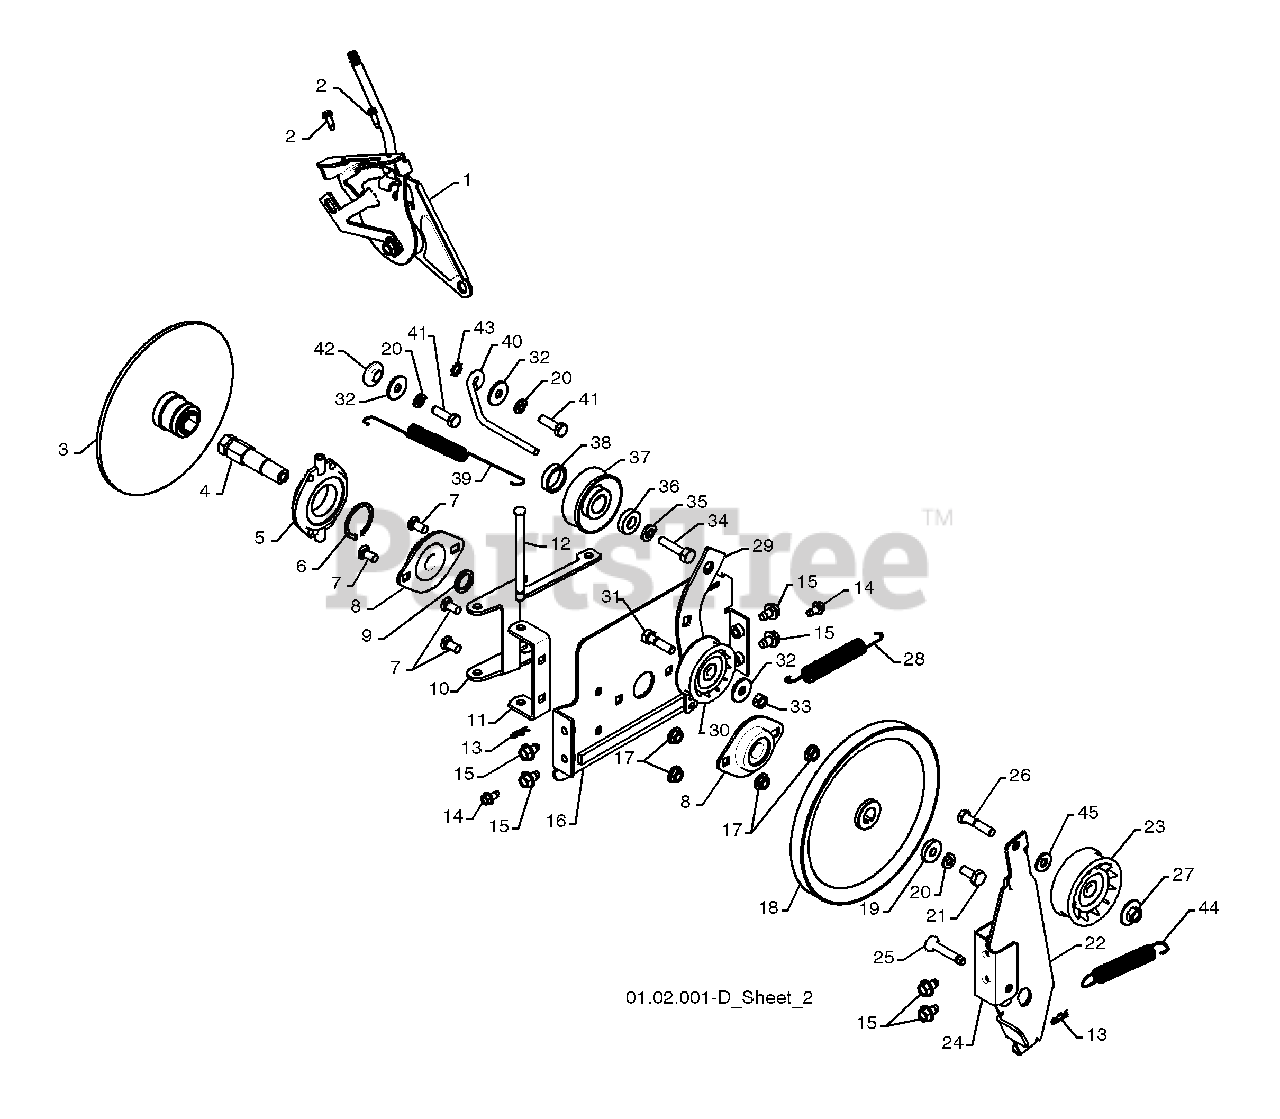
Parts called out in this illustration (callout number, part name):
1	SPEED SELECTOR HEAD ASSEMBLY
2	SCREW 10-24 X .625
3	DRIVE PLATE WELDMENT
5	TRUNNION BEARING ASSEMBLY
6	RETAINER
7	CARRIAGE BOLT 5/16-18 X .625
8	FLANGE BEARING
10	LEVER SHIFTER PLATE
11	SHIFTER SUPPORT BRACKET
14	SCREW 1/4-20 X .500
15	BOLT 5/16-18 X .500
16	DRIVE MOUNT PLATE
17	NUT 5/16-18
18	TRACTION PULLEY
20	LOCKWASHER 5/16
21	SCREW 5/16-18 X .750
22	IDLER BRAKE ARM
23	IDLER PULLEY
24	IDLER PIVOT BRACKET
26	SCREW 5/16-18 X 1.50
27	NUT 5/16-18
28	TRACTION SPRING
29	IDLER TRACTION ARM
30	IDLER PULLEY
31	SCREW 5/16-18 X 1.25
33	NUT 5/16-18
34	SCREW 3/8-24 X 1.38
35	LOCKWASHER 3/8
37	ENGINE TRACTION PULLEY
39	RETURN SPRING
40	BELT GUIDE
41	SCREW 5/16-18 X 1.00
42	BUSHING
43	LOCKWASHER 5/16
44	BRAKE SPRING
45	WASHER .20 x 8.5 x 2.0
